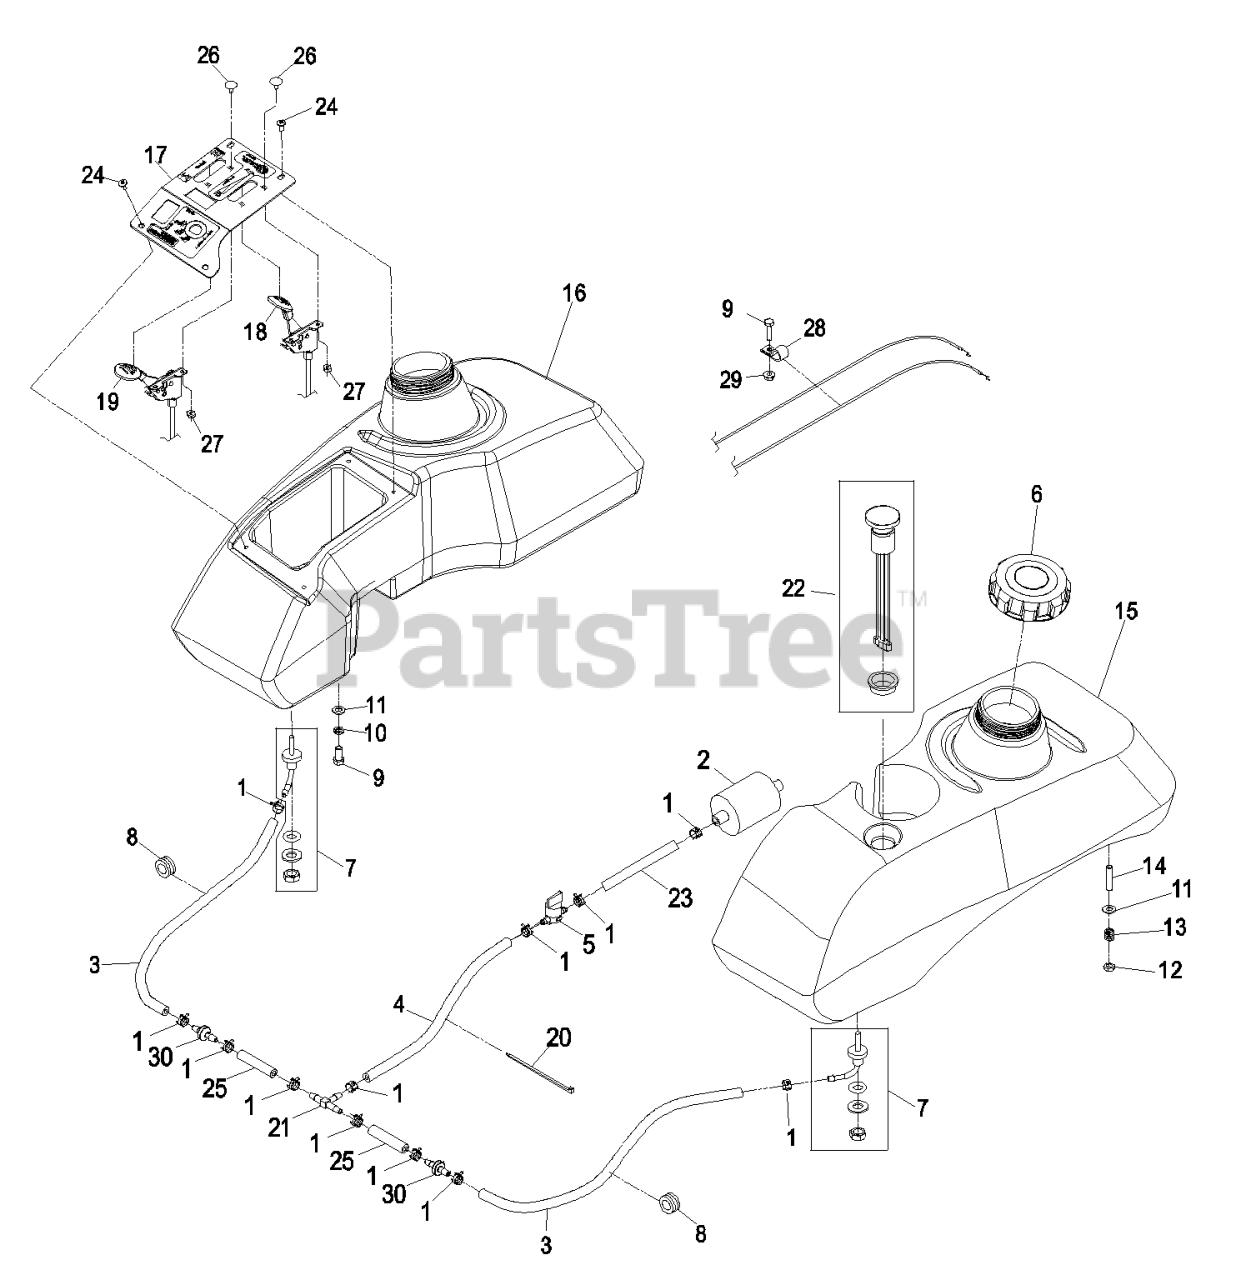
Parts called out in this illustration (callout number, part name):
2	Kohler Part No. 2405010 Fuel Filter
3	HOSE,FUEL
4	HOSE-FUEL
5	VALVE-FUEL
6	CAP-FUEL, GAS
7	FITTING-FUEL, BULKHEAD
8	GROMMET
9	SCREW-HH
10	WASHER-LOCK
11	WASHER-PLAIN
12	NUT-LOCK, NI
13	SPRING-TANK, FUEL
14	STUD
15	KIT,FUEL TANK LH LHP
16	ASM, LHP RH FUEL TANK S.O
17	PANEL,CONTROL W/DECALS
18	CONTROL-THROTTLE
19	CONTROL,CHOKE
20	TIE-PLASTIC
21	FITTING-TEE, BARBED
22	KIT, HP FUEL GAGE REPL.
23	HOSE-FUEL
24	SCREW-PPH
25	HOSE-FUEL
26	BOLT-CARR
27	NUT-LOCK, NI
28	CLIP-LOOM
30	VALVE-CHECK, FUEL
